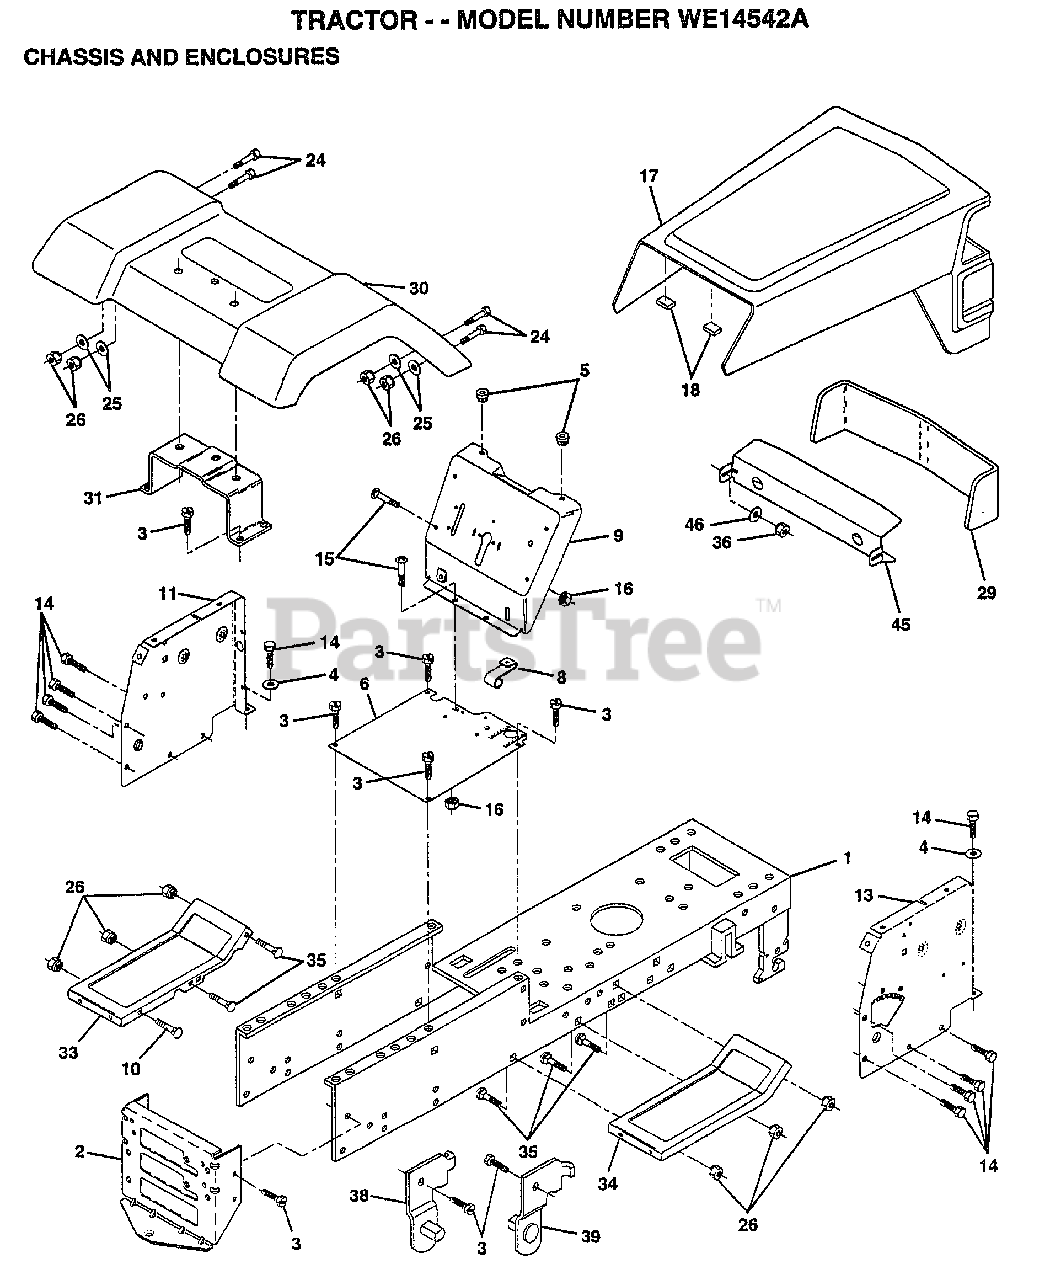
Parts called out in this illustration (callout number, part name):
1	CHASSIS.WLD.11GA
3	SCREW
4	WASHER
8	"CLIP,INSULATOR"
9	DASH.SLKSC.LT.1PC
11	PANEL.DASH.LH.
14	SCREW LT
15	SCREW
17	HOOD/GRILLE.ASM.
24	BOLT
25	WASHER
26	NUT
31	BRKT FENDER
33	FOOTREST.LH.LT/GT
34	FOOTREST.RH.LT/GT
35	BOLT
36	PAL NUT LT
38	BRACKET ASM LH
39	BRACKET ASM RH
46	RETAINER
